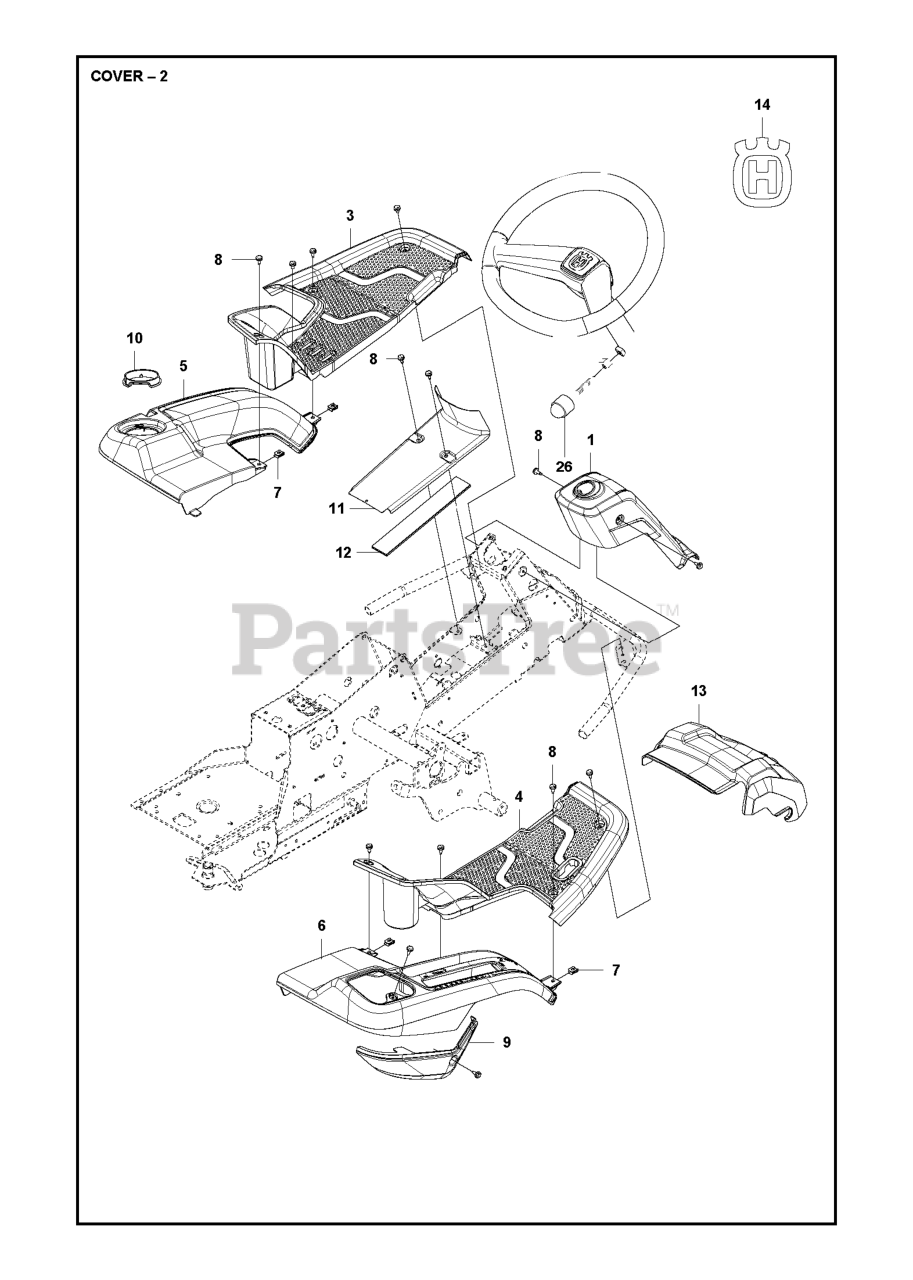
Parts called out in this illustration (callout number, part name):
3	FOOT PLATE
4	FOOT PLATE
9	CONTROL COVER
10	LOCKING NUT
12	MAT COVER FRAME
26	PROTECTIVE COVER
